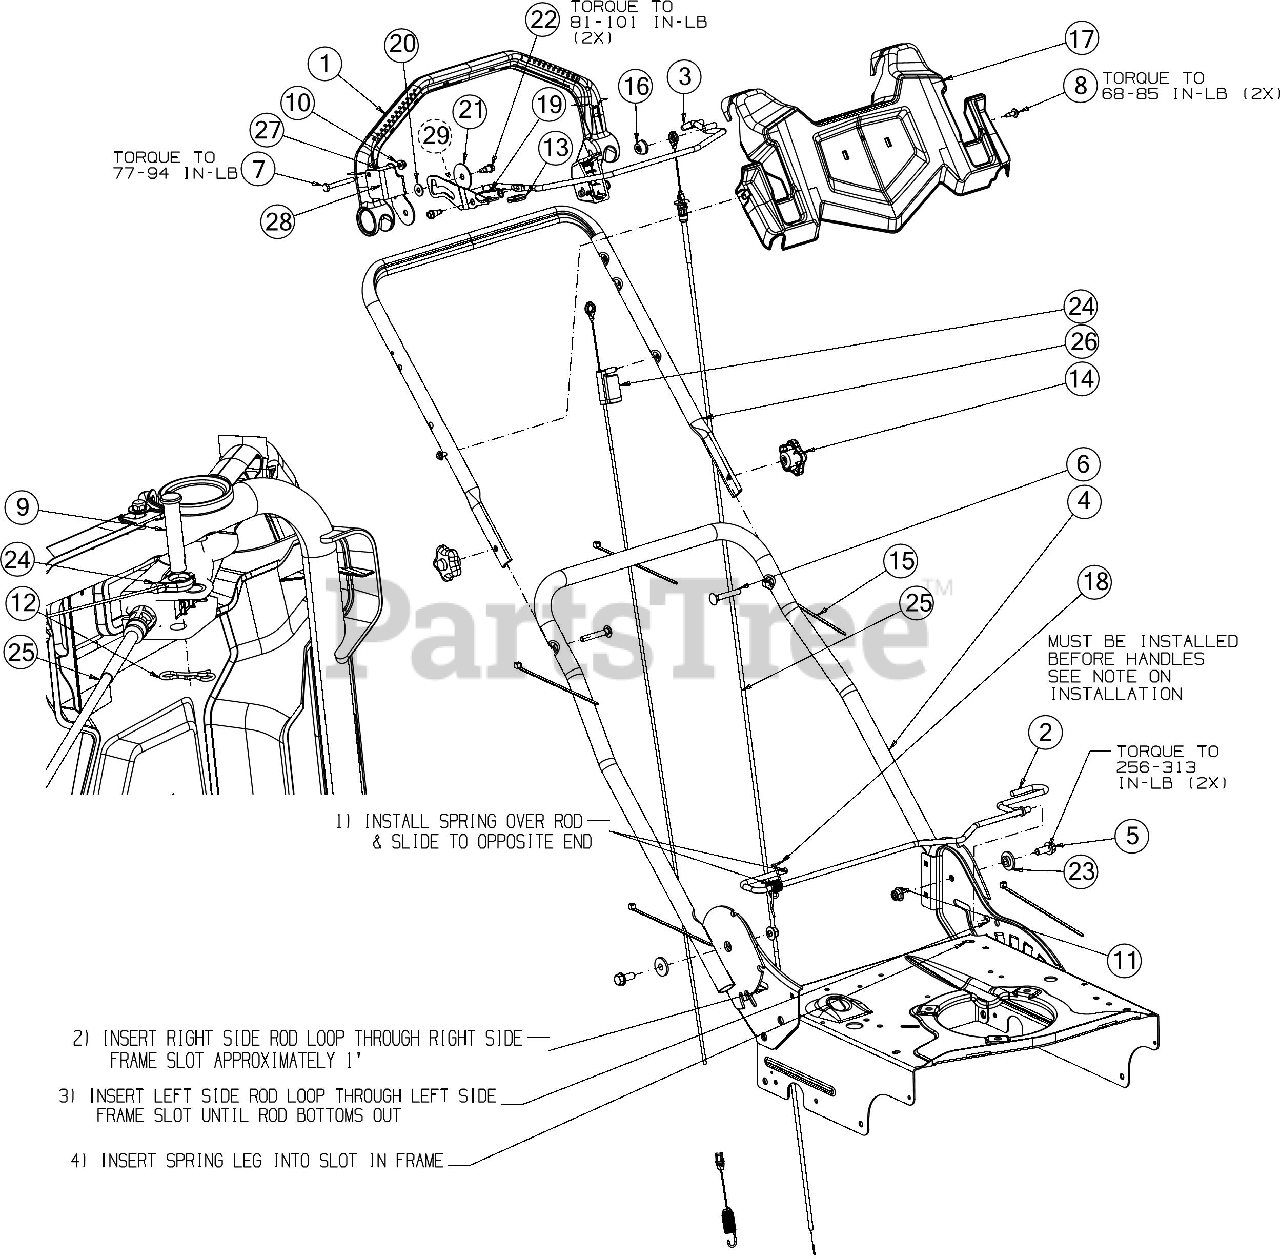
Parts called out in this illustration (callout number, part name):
1	DRIVE HANDLE ASSEMBLY (YELLOW)
5	SCREW 3/8-16 x .875 GR5
6	CARRIAGE BOLT 5/16-18 x 2.00 GR5
7	SCREW 1/4-20 x 2 GR5
8	SCREW M6-1 x .625
9	CLEVIS PIN 3/8 x 1.87
10	FLANGE LOCK NUT
12	BOW TIE COTTER PIN 1/4-5/16
14	STAR KNOB- YELLOW
15	7" CABLE TIE
16	PUSH CAP 0.3125
17	HANDLE CONSOLE
18	TORSION SPRING .48 x .177
19	TORSION SPRING
20	FLAT WASHER .28 ID x .74 OD x .063
21	FLAT WASHER .350X1.59X.062
22	SHOULDER SCREW
23	SHOULDER SPACER .625 x .169
24	DRIVE CABLE
25	CONTROL CABLE
27	SPACER:.260 x .372 x 1.420
29	LOCK OUT BRACKET
